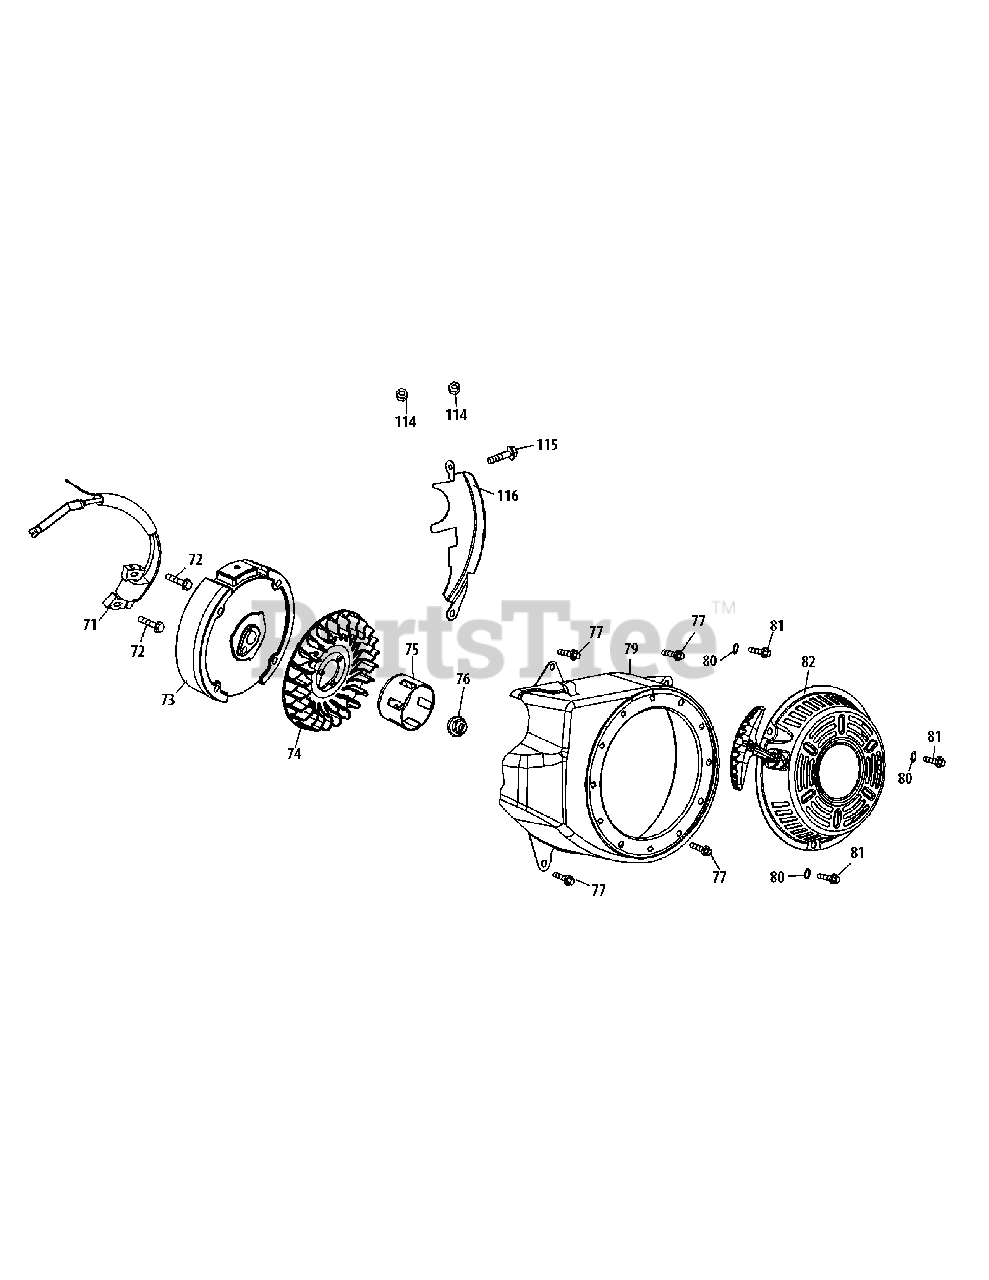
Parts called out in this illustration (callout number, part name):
71	Ignition Coil Assembly
72	Bolt M6×25
74	Fan, Cooling
75	Pulley, Starter
76	Nut, Special, M14×1.5
77	Bolt M6×12
79	Blower Housing
80	Washer
81	Bolt M6×10
82	Recoil Starter
114	Nut, M6
115	Bolt M6×20
116	Blower Housing Shield
